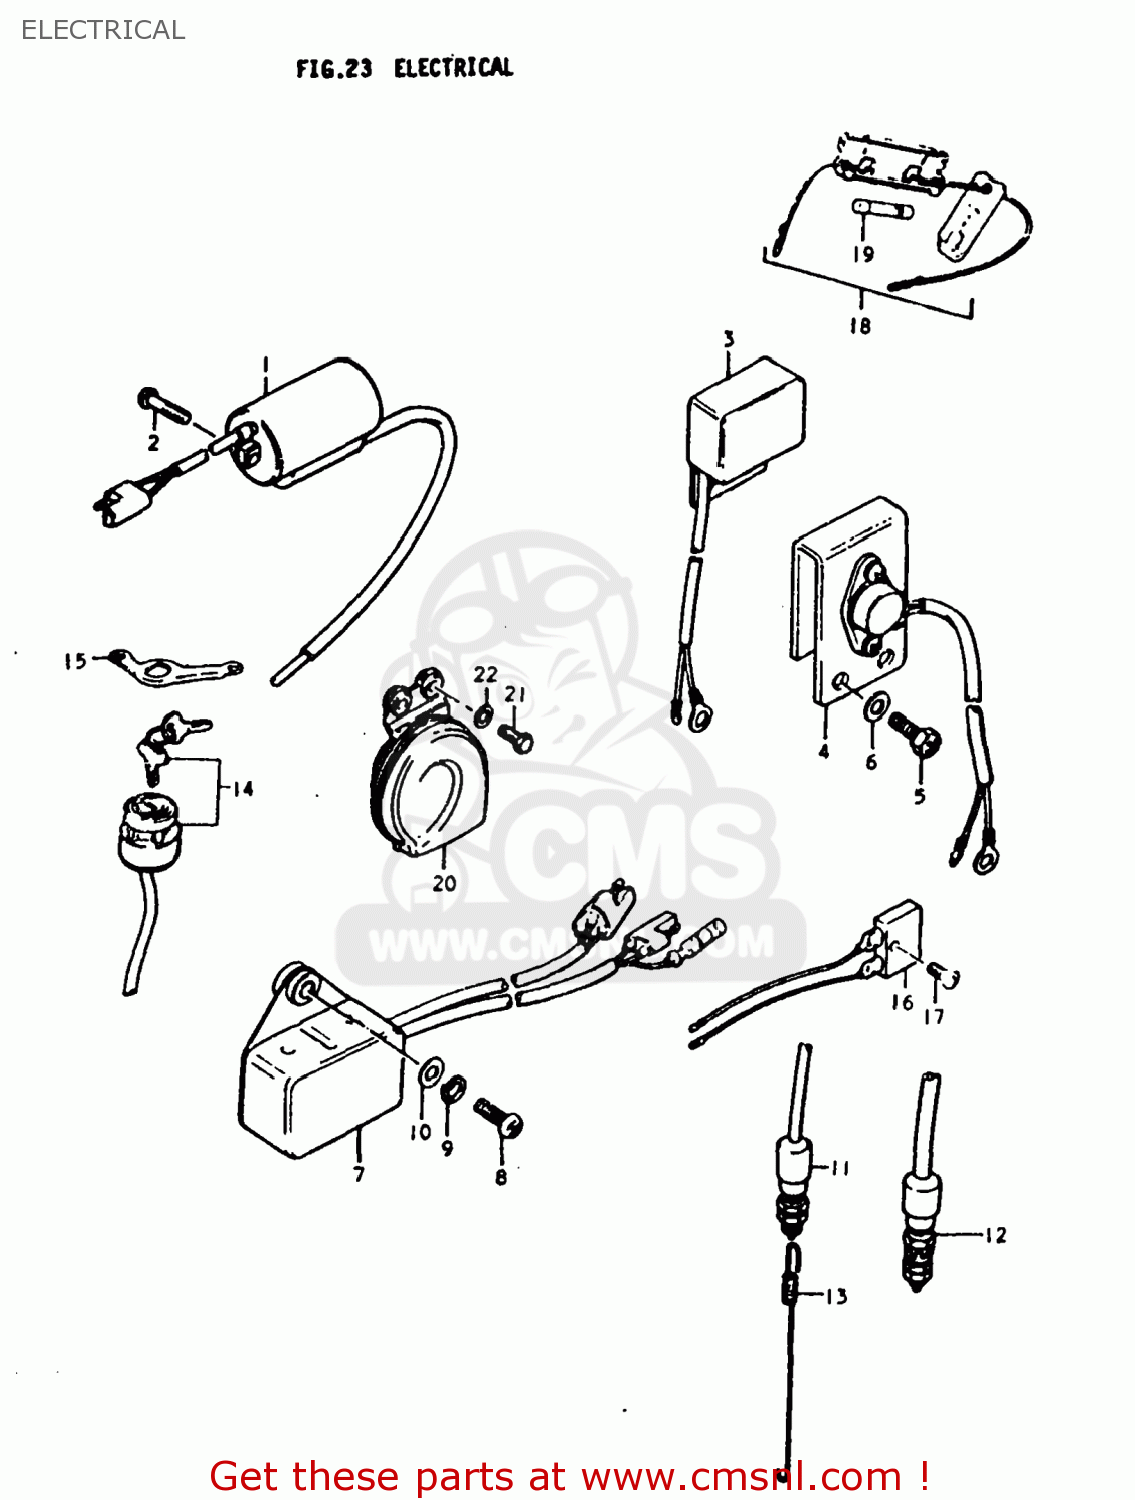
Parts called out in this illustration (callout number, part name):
1	COIL ASSY,IGNITION
2	SCREW 5X20
3	REGULATOR ASSEMBLY
4	REGULATOR ASSEMBLY
5	SCREW(5X12)
6	WASHER
7	CDI UNIT
8	SCREW
9	LOCK WASHER
10	WASHER
11	SWITCH ASSY, STOP LAMP
12	SWITCH ASSEMBLY,STOP LAMP
13	SPRING
14	SWITCH ASSEMBLY,IGNITION
15	BRACKET,IGNITION SWITCH
16	RECTIFIER ASSEMBLY
17	SCREW
18	BOX ASSEMBLY,FUSE
19	FUSE(15A)
20	HORN ASSY
21	BOLT
22	WASHER
